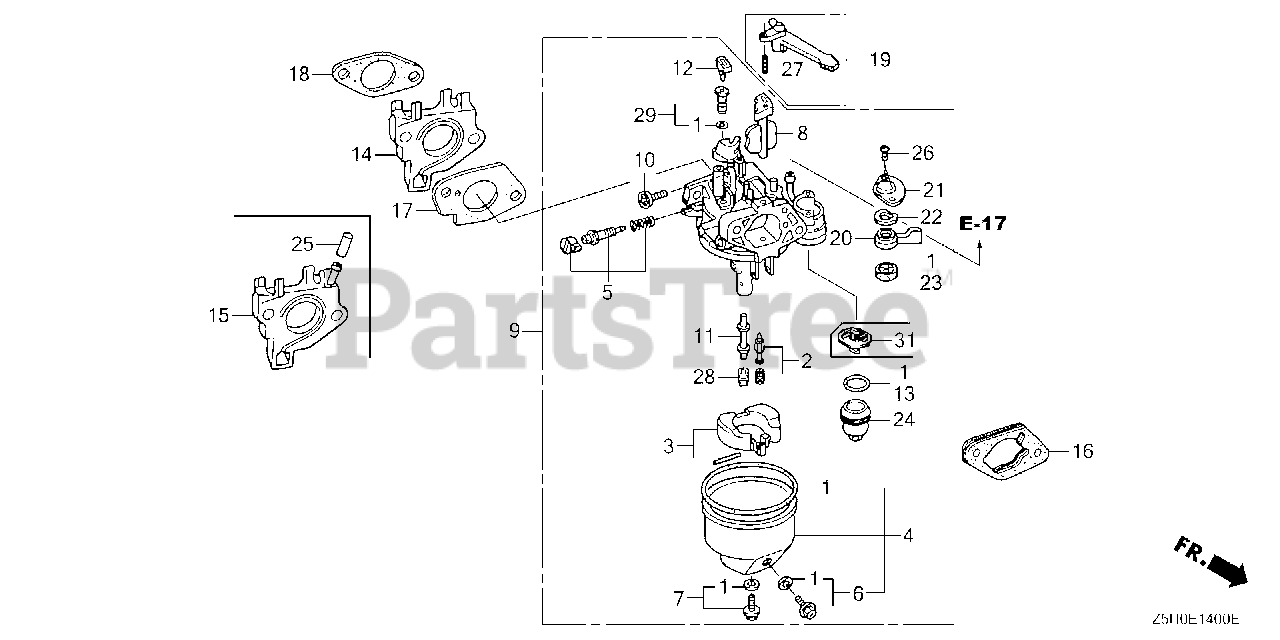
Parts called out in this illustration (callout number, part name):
1	GASKET SET (INCLUDES 16173-001-004)
2	VALVE SET, FLOAT
4	CHAMBER SET, FLOAT
5	SCREW SET, PILOT
6	SCREW SET, DRAIN
7	SCREW SET
9	CARBURETOR ASSY. (BE75A B/C)
10	SCREW, THROTTLE STOP
11	NOZZLE, MAIN
12	COLLAR, SETTING
13	GASKET, FUEL STRAINER CUP
14	INSULATOR, CARBURETOR
16	SPACER, CARBURETOR
17	GASKET, CARBURETOR
18	GASKET, INSULATOR
19	LEVER, CHOKE (STD)
20	LEVER, PETCOCK
21	PLATE, LEVER SETTING
22	SPRING, PETCOCK LEVER
23	GASKET, PETCOCK
24	CUP, FUEL STRAINER
26	SCREW, PAN (3X6)
27	PIN, SPRING (2X12)
28	JET, MAIN (#88)
28	JET, MAIN (#90)
28	JET, MAIN (#92)
29	JET SET, PILOT (#35) (CARBURETOR NO.)
29	JET SET, PILOT (#40) (CARBURETOR NO.)
